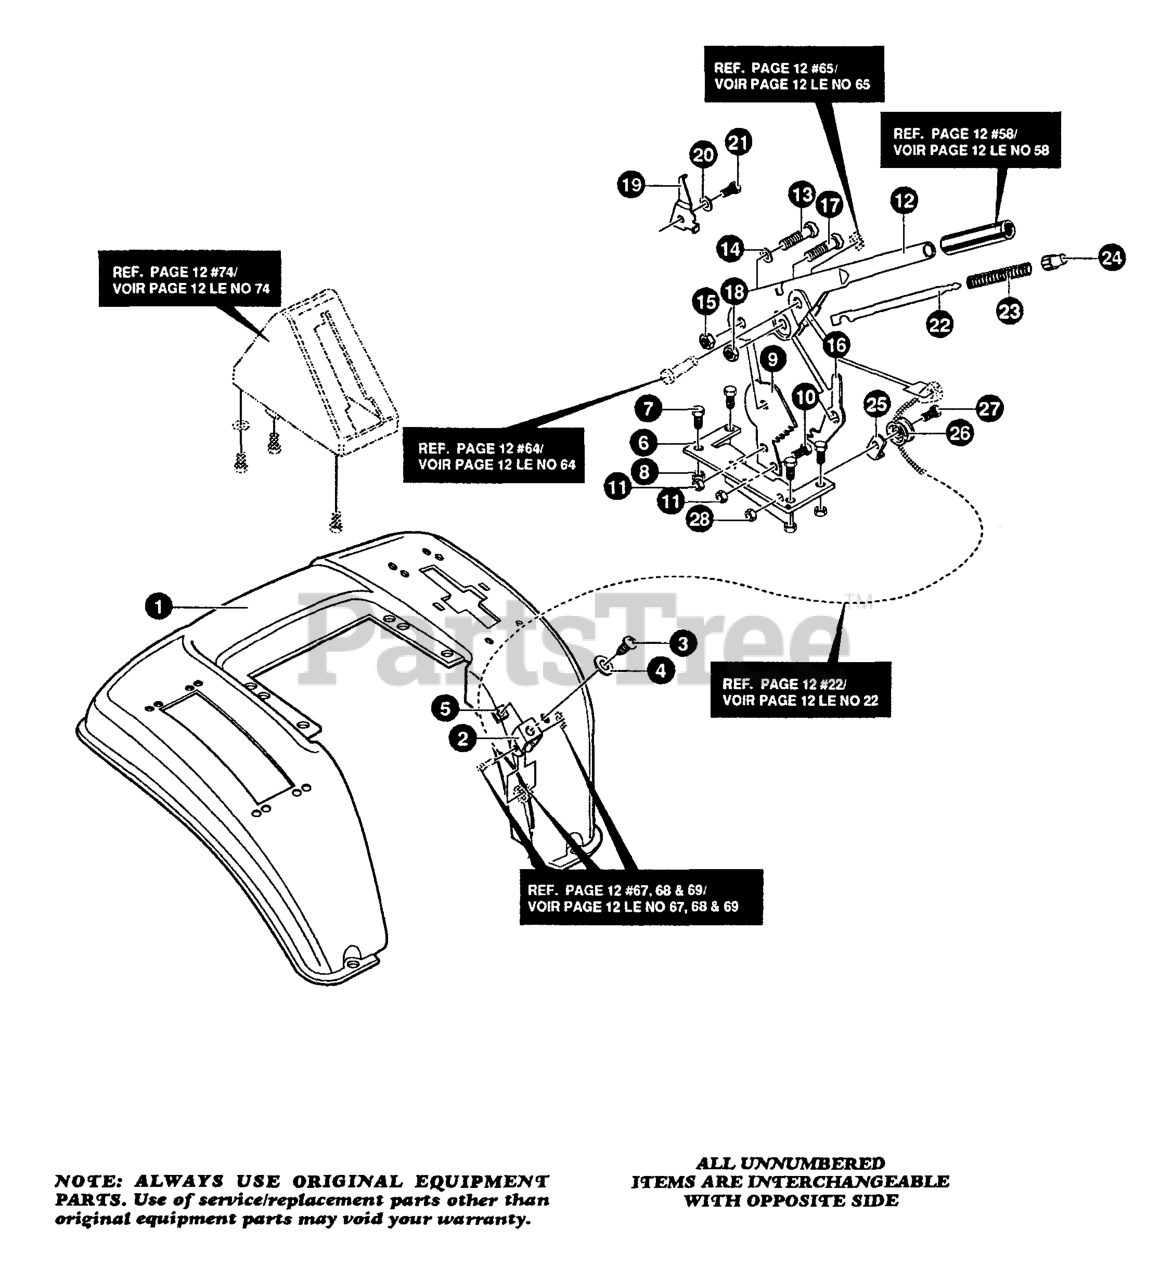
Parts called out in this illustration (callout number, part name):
2	CLEVIS
4	WASHER
6	BRKT, HEIGHT ADJUST
7	SCREW
9	QUADRANT
10	SCREW
12	HANDLE, LIFT
14	WASHER
16	PAWL, SQUARE
19	POINTER
20	WASHER
21	SCREW
22	ROD, ACTUATOR
23	SPRING, HEIGHT ADJUST
25	CABLE BRACKET
